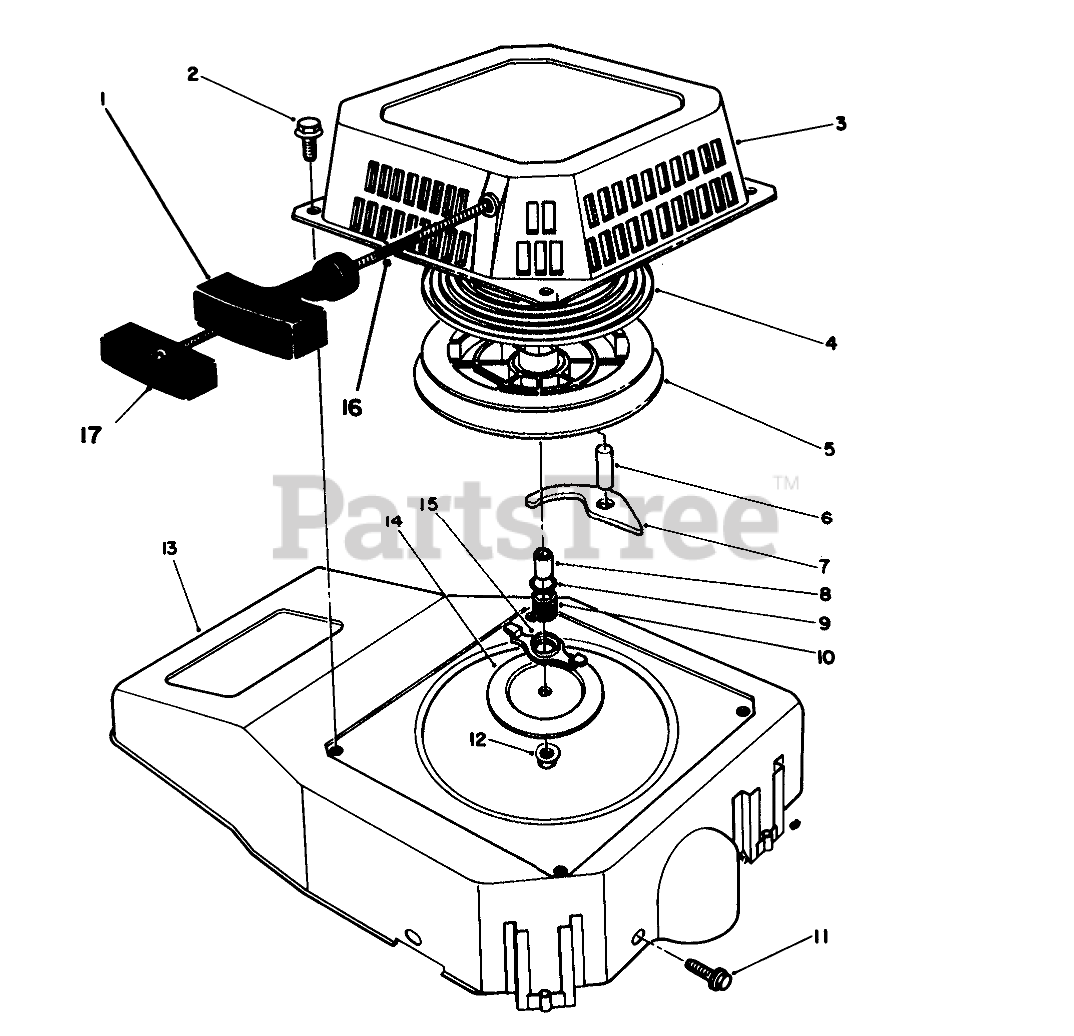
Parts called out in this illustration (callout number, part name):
1	HANDLE
2	SCREW-HHF
3	Case-Recoil
4	SPRING
8	Spacer
9	WASHER
10	Spring-Friction
13	SHROUD
14	PLATE
15	Guide-Paw
16	ROPE-STARTER
17	RETAINER HANDLE
